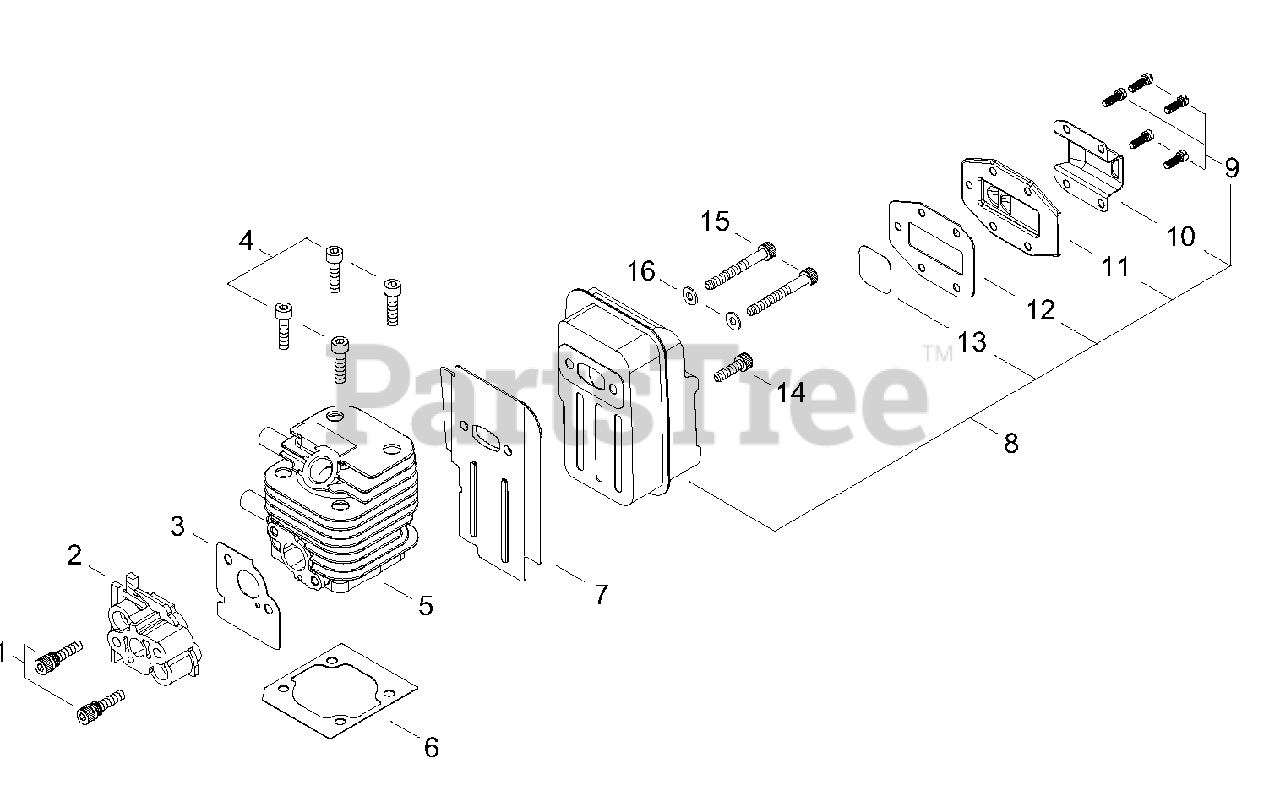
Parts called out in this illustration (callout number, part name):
1	BOLT SS M5×30
2	INSULATOR
3	HEAT SHIELD, INTAKE
4	BOLT 5×16
5	CYLINDER
6	GASKET, CYLINDER
7	HEAT SHIELD, EXHAUST
8	MUFFLER ASSY
9	SCREW M4×8
10	OUTLET, EXHAUST
11	COVER, SPARK ARRESTER
12	GASKET, EXHAUST
13	SCREEN, SPARK ARRESTER
14	BOLT 5×12
15	BOLT M5×55
16	WASHER SS 5 MM
